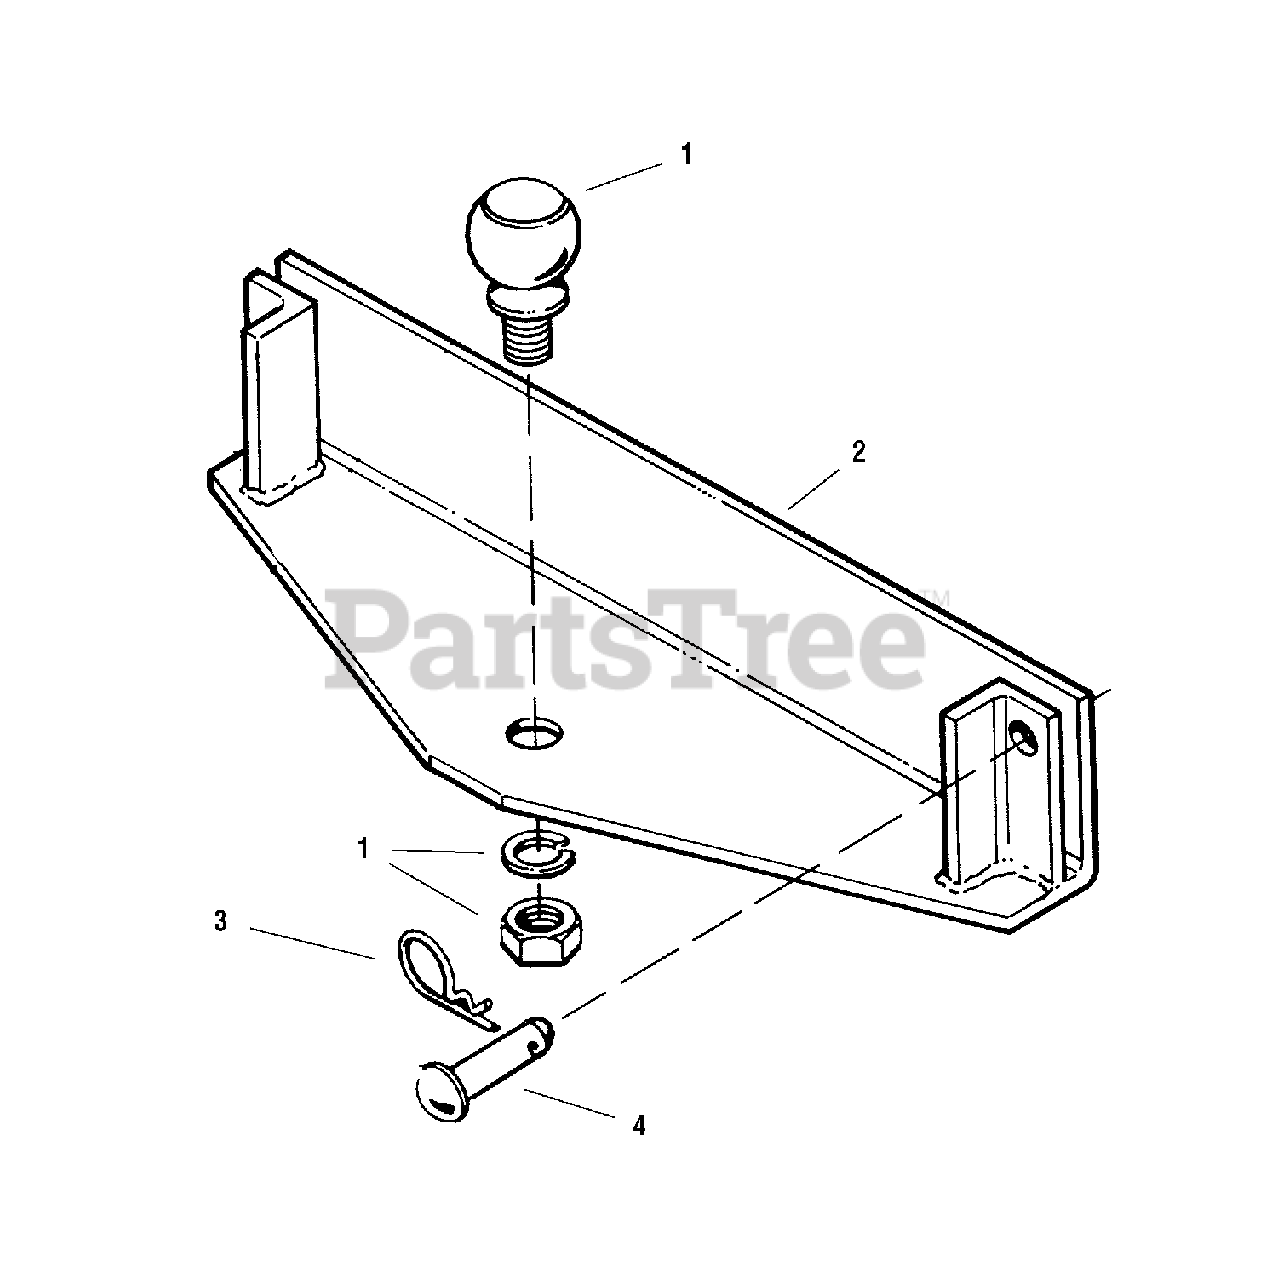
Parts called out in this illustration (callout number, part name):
1	BALL HITCH
2	HITCH ASSEMBLY FRONT
3	SPRING CLIP
4	PIN
